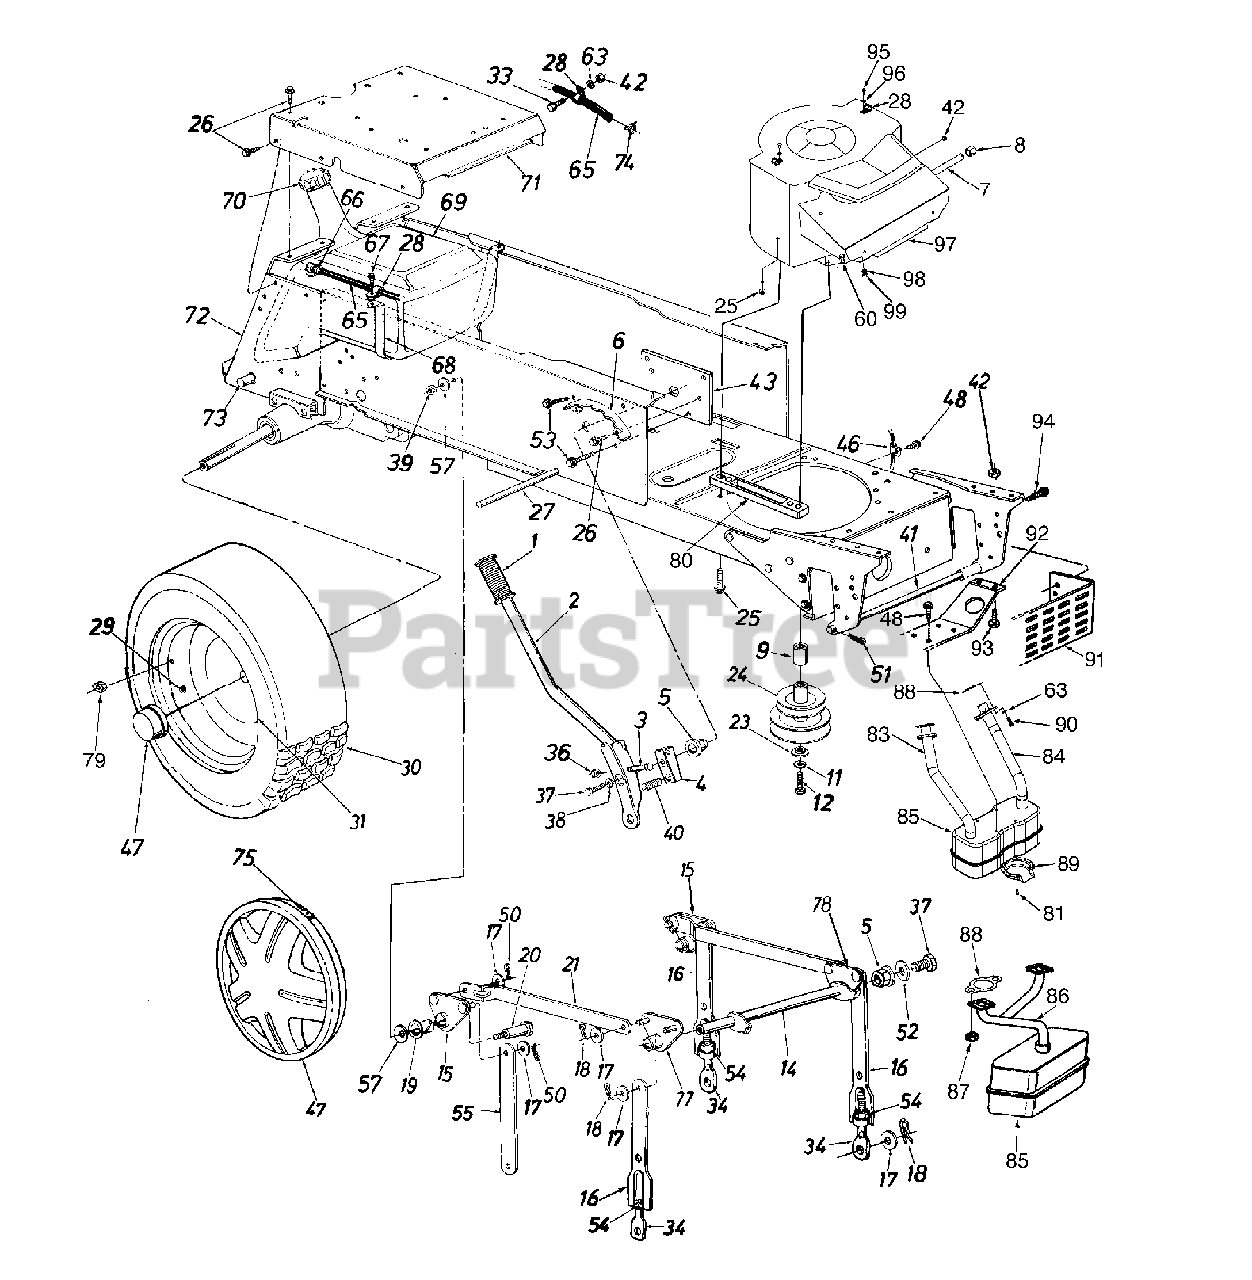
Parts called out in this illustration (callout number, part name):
1	Grip
4	Lift Shaft Drive
5	Plastic Hex Brg. 5/8" I.D.
8	Pipe Cap 3/8-18 Npt.
9	Spacer
11	L-Wash. 7/16" I.D.
12	Hex Scr. 7/16-20 x 2" Lg. (Gr. 5)
14	Lift Shaft Ass'y.
15	Lift Pivot Brkt. Ass'y.
17	Fl-Wash. 1/2" I.D. x 1.00" O.D. x .090"
18	Hairpin Cotter
19	Nyliner 5/8" I.D. x .88" Lg.
20	Shld. Bolt 5/8" Dia. x .96" Lg. 3/8-16
24	Engine Pulley
25	Hx Wash Hd. Scr. 3/8-16 x 1.25" Lg.
26	Hex Thd. Rolling Scr. 5/16-18 x .75" Lg.
27	Running Board Rod
28	Clamp
29	Air Valve 23" x 9.5" Round/Square Shoulder
33	Hex Bolt 1/4-20 x .62" Lg.
34	Eye Bolt Adj. Link 1/2-13 Thd.
36	Hex Cent. L-Nut 5/16-18 Thd.
37	Hex Bolt 5/16-24 x .62" Lg.
38	L-Wash. 5/16" I.D.
39	Hex Top L-Nut 3/8-16 Thd.
40	Compression Spring
41	Deck Connecting Rod
42	Hex Sems Nut 1/4-20 Thd.
47	Hub Cap
48	Hx Wash Hd. TT-Tap Scr. 1/4-20 x .5" L
50	Cotter Pin .09 Dia. x 1.0" Lg.
51	Int. Cotter Pin
52	Fl Wash. .34" I.D. x 1.12" O.D. x .125"
53	Hx Wash Hd AB-Tap Scr 5/16-24 x .5" L
54	Hex Nut 1/2-13 Thd.
57	Bell-Wash. .4" I.D. x 1.13" O.D.
60	Hex Bolt 5/16-18 x .75" Lg.
63	L-Wash. 1/4" I.D.
65	Fuel Line 46" Lg.
66	Hose Clamp
67	Hex AB-Tap Scr. 1/4 x .62" Lg.
68	Fuel Tank Strap
69	Gas Tank
70	Gas Gauge
71	Seat Plate
74	Hose Clamp
75	Spring Clip (Optional)
77	Pivot Brkt. Ass'y.-R.H.
78	Pivot Brkt. Ass'y.-L.H.
79	Lug Nut 7/16-14 Thd.
80	Engine Mounting Spacer
81	Hex Hd. F-Tap Scr. #8-32 x .38" Lg.
83	Exhaust Tube-R.H.
84	Exhaust Tube-L.H.
85	Muffler
86	Exhaust Pipe
87	Flange Nut M8 x 1.25 Thd.
88	Exhaust Gasket
89	Muffler Deflector
90	Hex Bolt 1/4-20 x .75" Lg.
93	Hex Bolt 1/4-20 x .62" Lg.
94	Hex TT-Tap Scr. 5/16-18 x .62" Lg.
95	Truss Mach. B-Tap Scr. #10 x .5" Lg.
96	Fl-Wash. .188" I.D. x .438" O.D.
99	Hex Nut 5/16-18 Thd. (Gr. 5)
